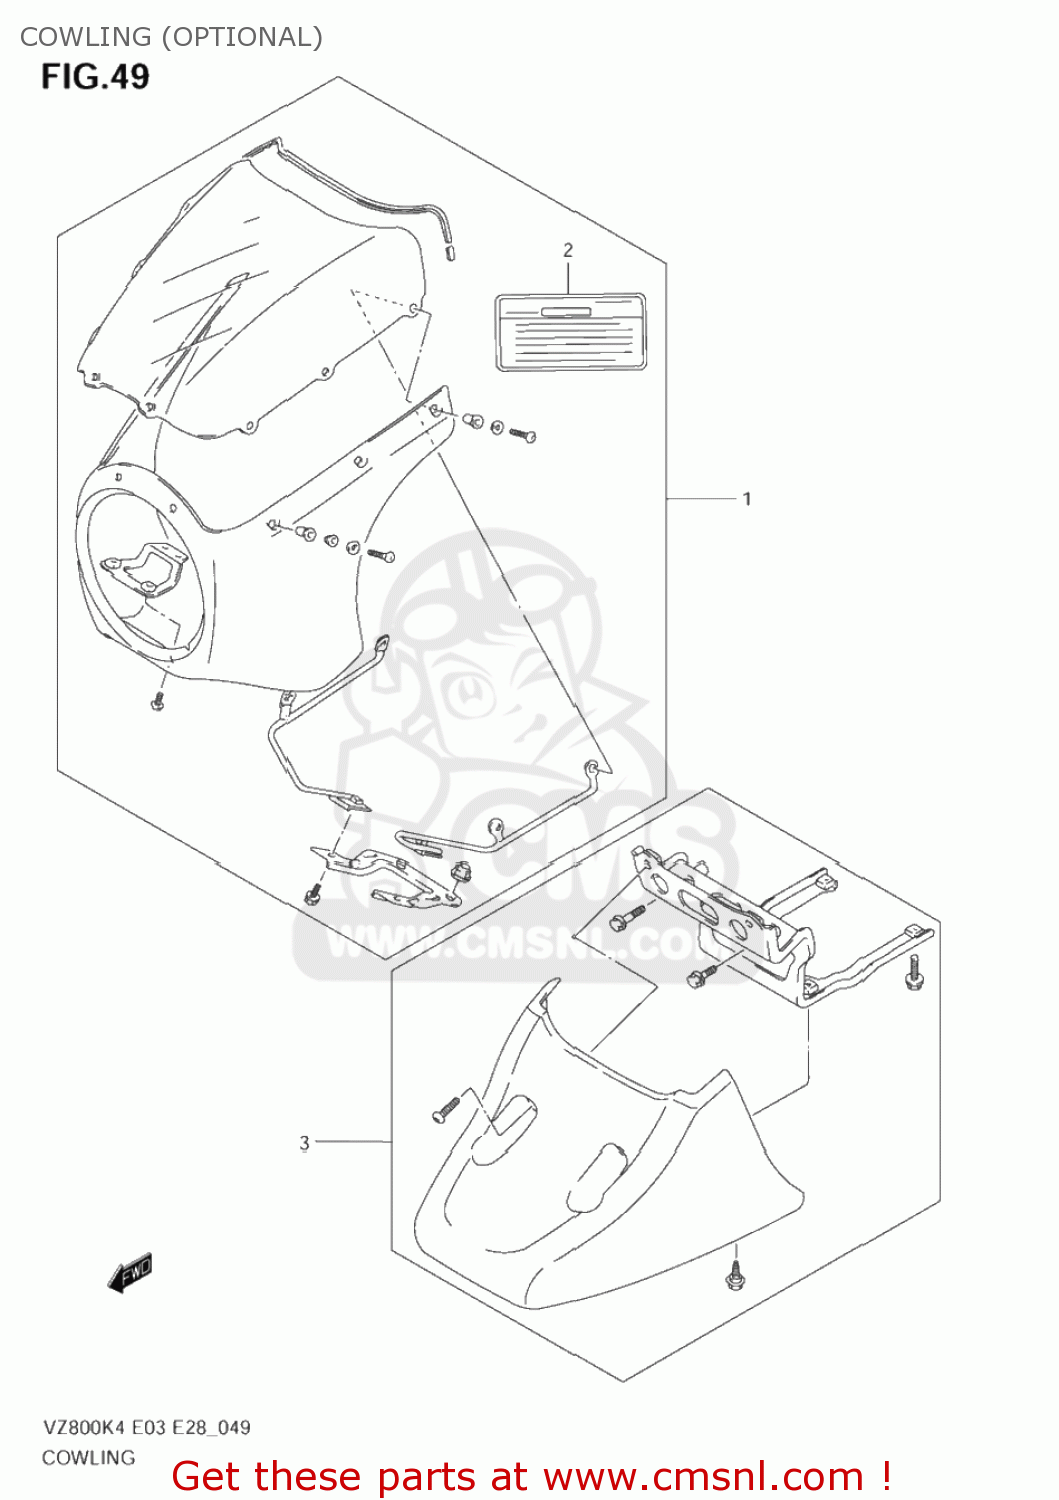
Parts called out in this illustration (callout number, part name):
1	COWLING SET,BODY
2	LABEL,WARNING SCREEN
3	COWLING,UNDER(BLUE)
